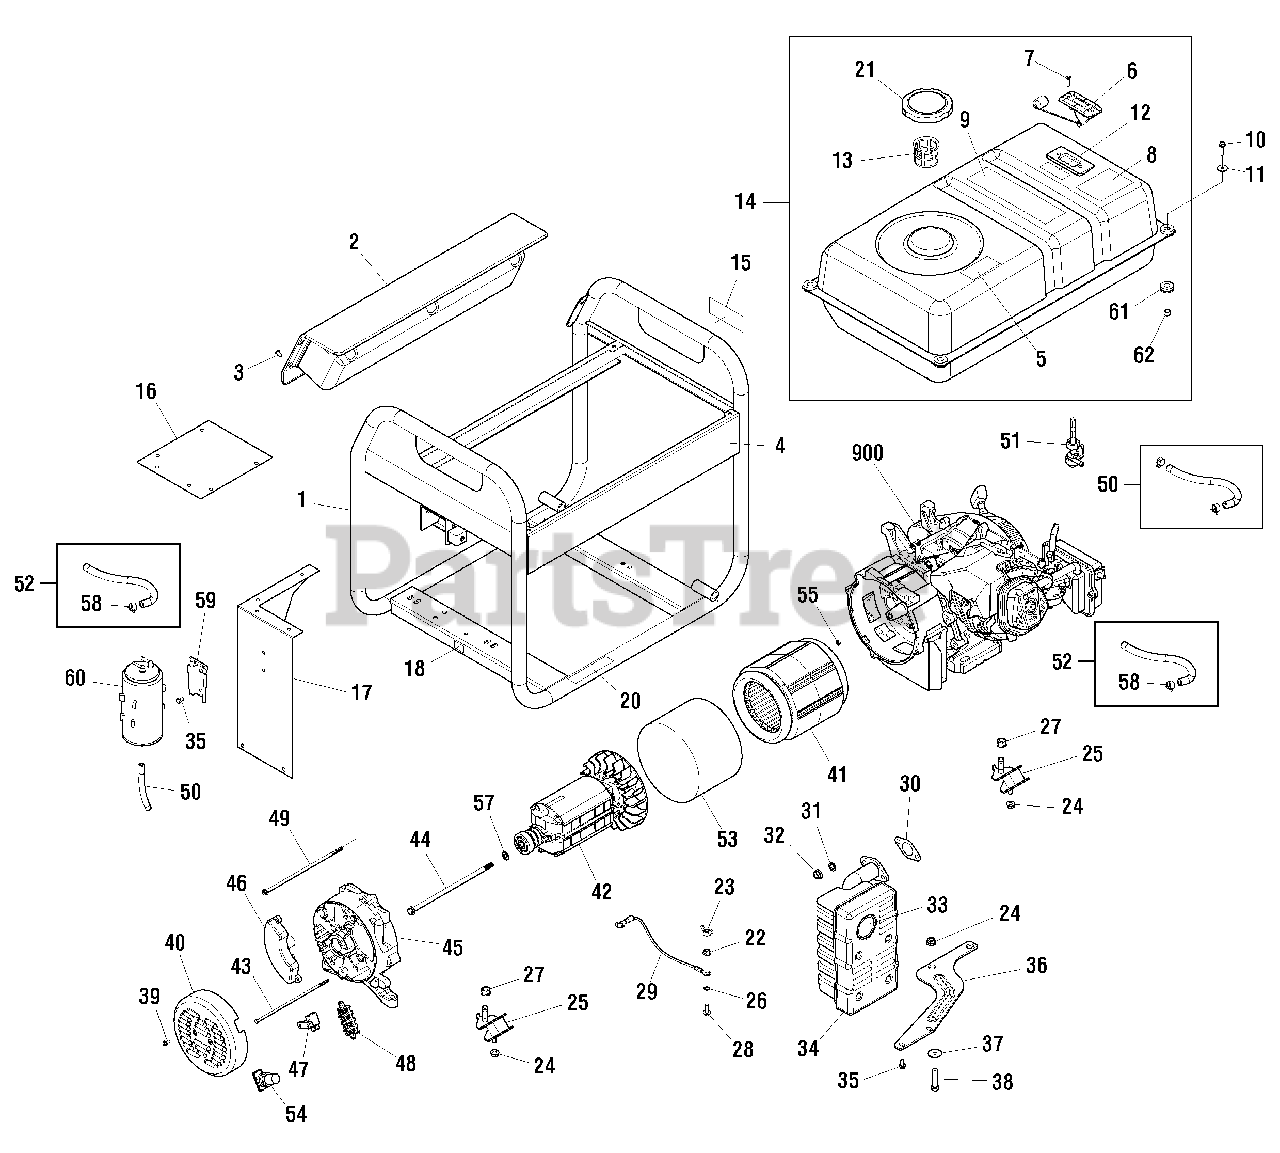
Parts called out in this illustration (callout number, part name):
2	PANEL-CONTROL
22	* NUT, Flange Lock, M6
24	* NUT, Flange Lock, M8
25	MOUNT-VIBRATION
26	* WASHER, Ext, Shakeproof, M6
27	* NUT, Flange Lock, M10
28	* SCREW, Flange, M6 x 16
30	GASKET
31	* WASHER, Lock, M8
32	* NUT, Hex, M8 1.25
35	* SCREW, Flange, M6 x 12
36	BRACKET-MUFFLER
37	* WASHER, Flat, M8
38	HHCS-M8-1.25 x 40
45	CARRIER-BEARING
46	VOLTAGE REGULATOR
50	KIT-FUEL HOSE
52	HOSE-VAPOR
900	** ENGINE
